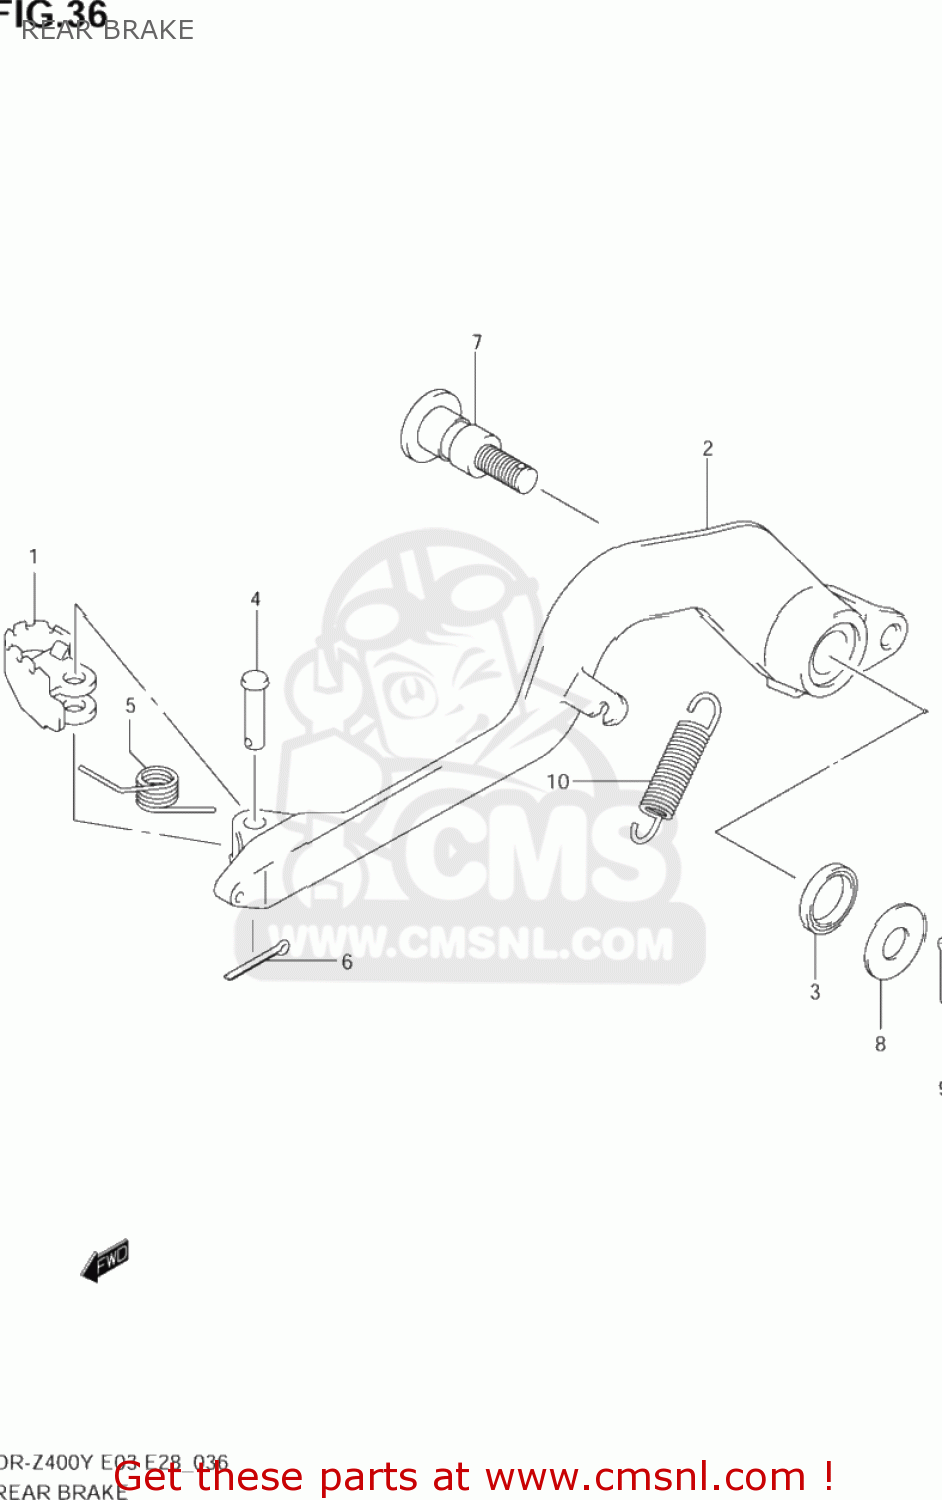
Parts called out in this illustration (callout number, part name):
1	PEDAL,BRAKE
2	ARM,BRAKE PEDAL
3	SEAL,OIL(15X21X3)
4	PIN(6X23.5)
5	SPRING
6	PIN
7	SHAFT,BRAKE PEDAL
8	WASHER
9	PIN 20X20
10	SPRING
